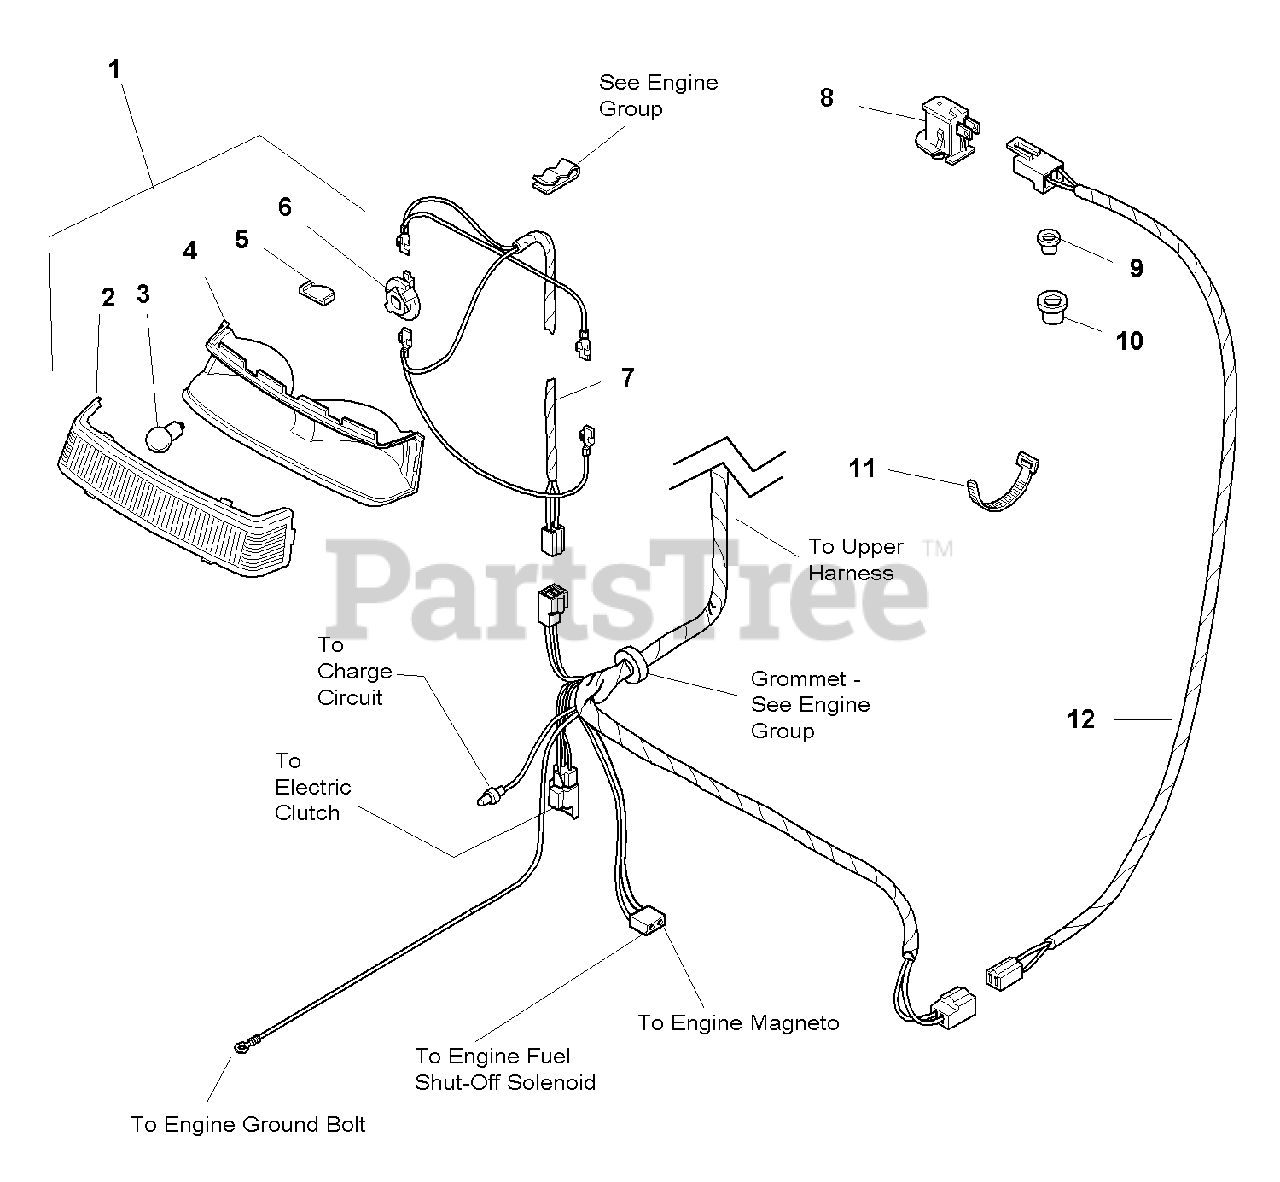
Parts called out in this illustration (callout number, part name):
1	HEADLIGHT ASSEMBLY (Includes Ref. Nos. 2, 3, 4, 5 & 6)
2	LENS, Headlight
3	BULB, Headlight, 12.8V
4	BEZEL, Headlight
5	HEAT SHIELD
6	SOCKET, Bulb
7	WIRE ASSEMBLY, Headlight
8	SWITCH, Seat, Operator Present
9	BUSHING, Snap, Small
10	BUSHING, Snap, Large
12	WIRE ASSEMBLY, Seat Switch
